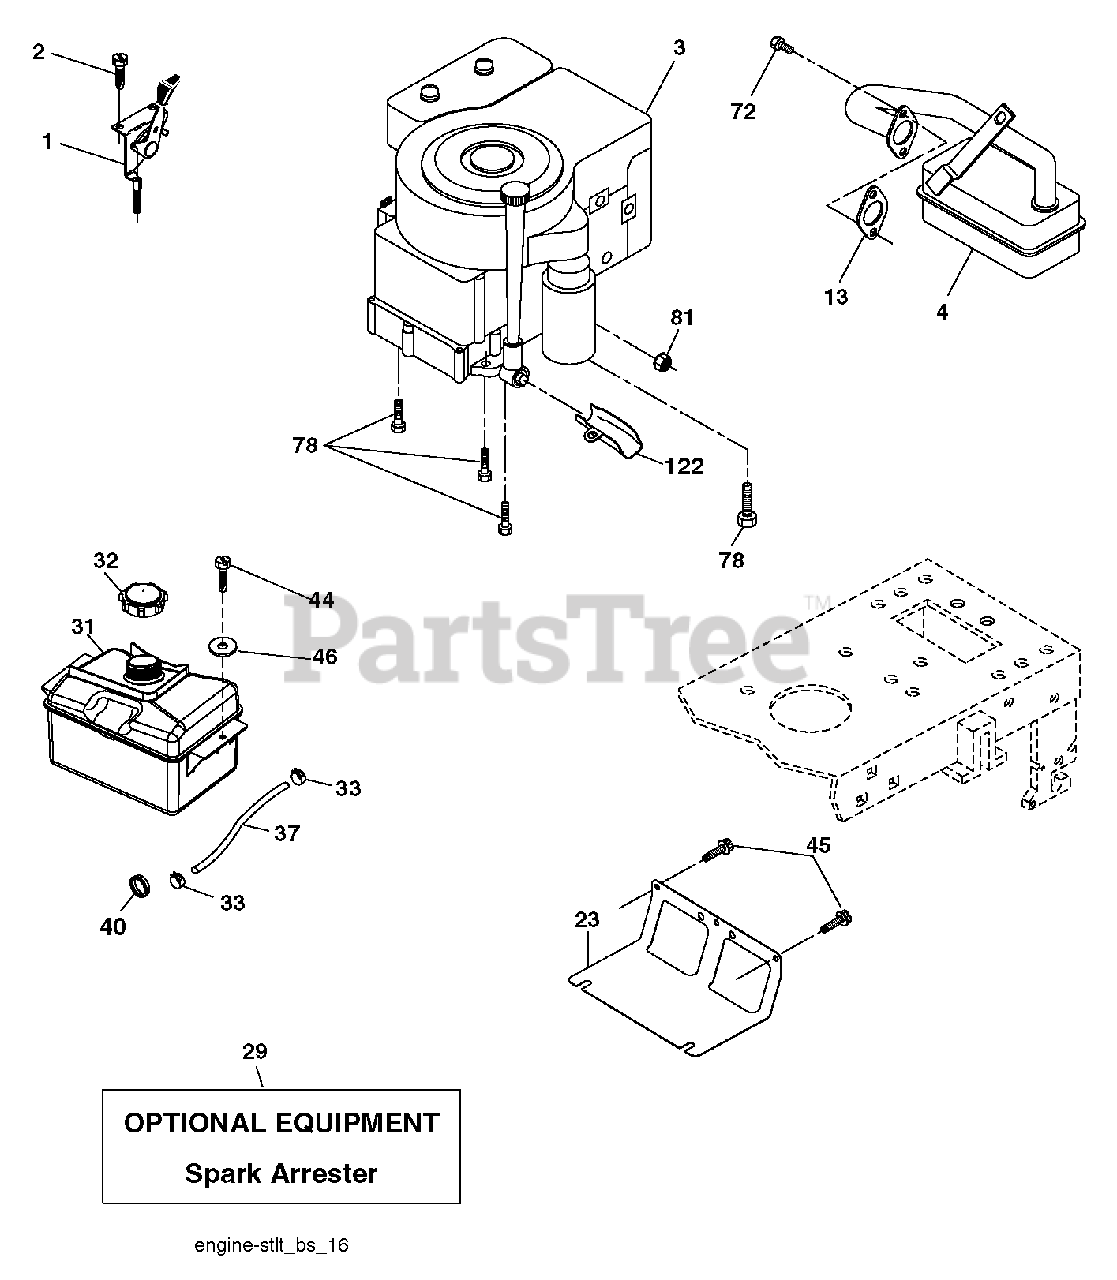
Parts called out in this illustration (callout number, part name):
1	CONTROL.THROTTLE/CHOKE.BLACK
2	SCREW
4	MUFFLER.LT.BRIGGS.14HP.IC/OHV
23	SHIELD.BROWNING.DBR.GUARD
29	KIT.SPARK ARRESTOR(392390 B&S)
31	RP TANK FUEL FRT 1.5 GAL
32	CAP ASM.FUEL.2.25"FR.
33	HOSE CLAMP
37	LINE.FUEL.20"FRONT.EMI
40	GROMMET T
44	SCREW HEXWSHR 1/4-20X3/4
45	SCREW, 3/8-16X3/4
46	WASHER
72	SCREW.SOCKET HD.5/16-1
78	SCREW.3/8-16
81	NUT
122	EXTENSION DRAIN OIL
